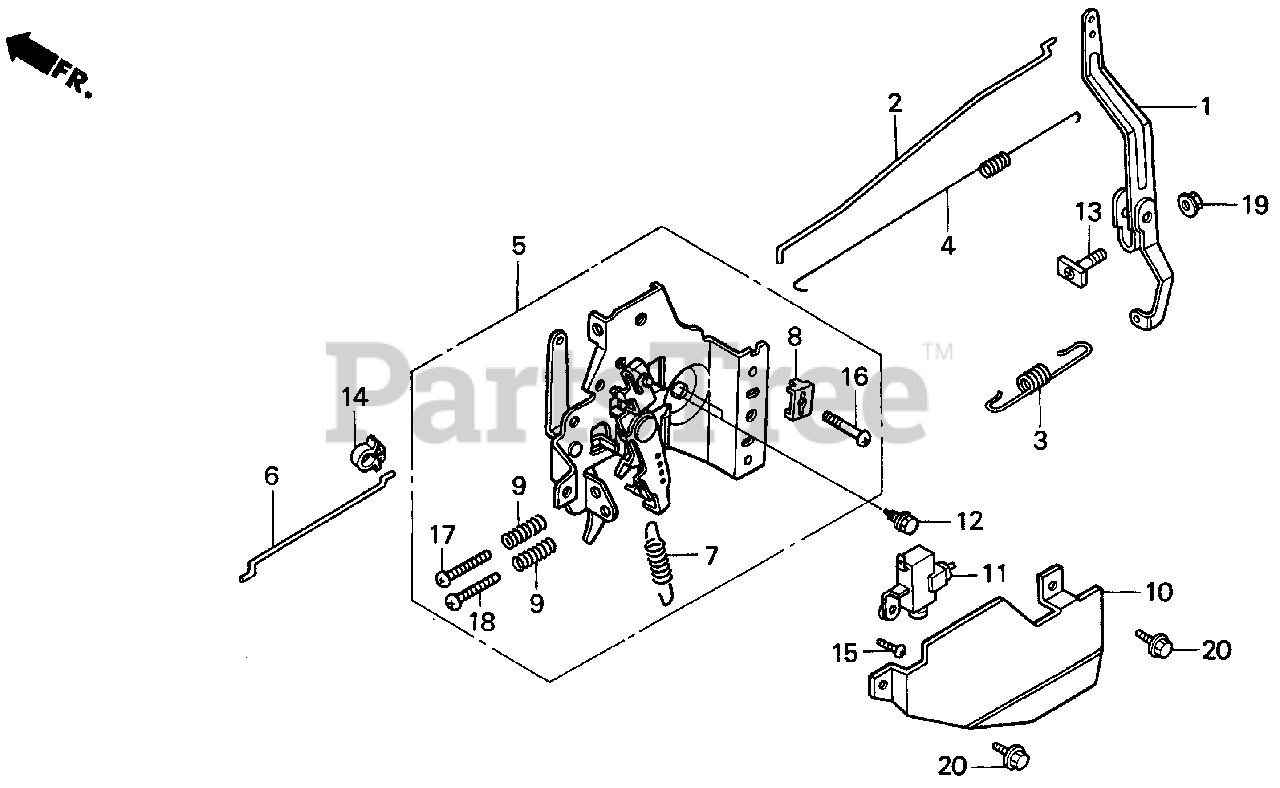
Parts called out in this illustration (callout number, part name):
1	ARM, GOVERNOR
2	ROD, GOVERNOR
3	SPRING, GOVERNOR (STD)
4	SPRING, THROTTLE RETURN
5	CONTROL ASSY.
6	ROD, CHOKE
7	SPRING, LEVER
8	HOLDER, CABLE
9	SPRING, CONTROL ADJUSTING
10	PROTECTOR, CONTROL
11	SWITCH ASSY., ENGINE STOP
12	BOLT, FLANGE (6X12) (CT200)
13	BOLT, GOVERNOR ARM
14	CLIP, WIRE HARNESS
15	SCREW, PAN (4X8)
16	SCREW, PAN (5X16)
17	SCREW, PAN (5X20)
18	SCREW, PAN (5X28)
19	NUT, FLANGE (6MM)
20	BOLT, FLANGE (6X10)
